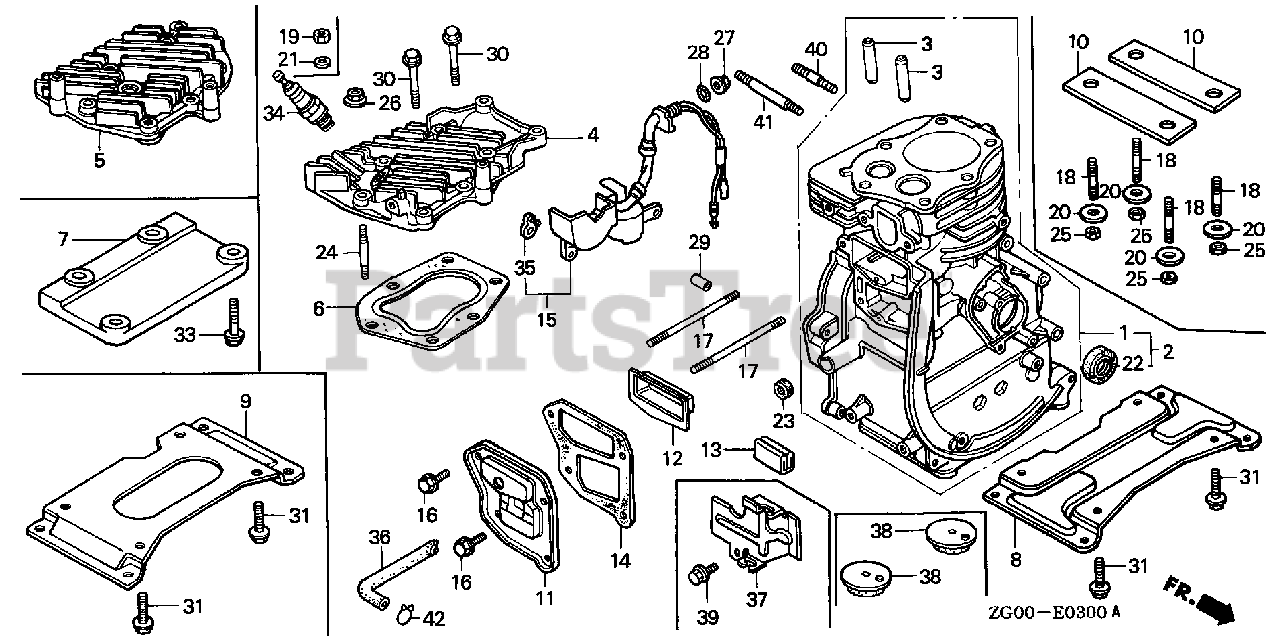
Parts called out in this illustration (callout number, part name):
2	CYLINDER ASSY.
3	GUIDE, VALVE (OS)
4	CYLINDER HEAD
6	GASKET, CYLINDER HEAD
8	BED, ENGINE (Q-TYPE)
11	COVER, TAPPET ROOM
12	SEPARATOR (INNER)
14	GASKET, TAPPET COVER
16	BOLT, FLANGE (5X10)
17	BOLT, STUD (5X80)
22	OIL SEAL (17X30X6) (NOK)
29	PIN A, DOWEL (8X14) (YAMADA)
30	BOLT, FLANGE (6X35)
31	BOLT, FLANGE (8X18)
34	SPARK PLUG (BPMR4A) (NGK)
